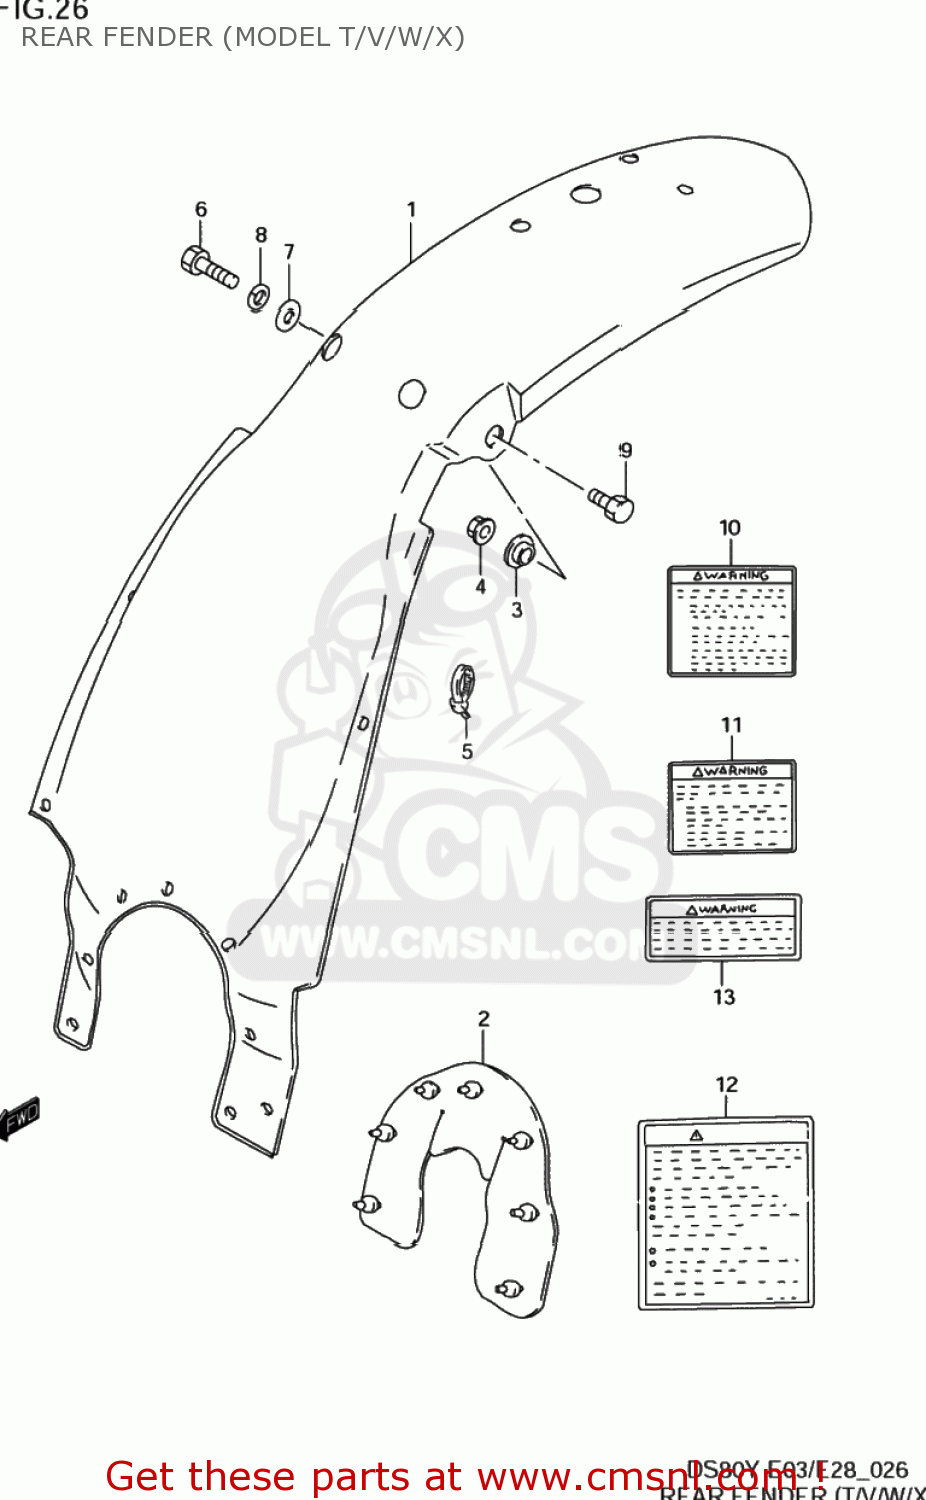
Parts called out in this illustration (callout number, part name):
1	FENDER,RR
2	MUDGUARD,RR FENDER
3	WASHER
4	NUT
5	CLAMP
6	BOLT
7	WASHER(8.5X28X1.6)
8	LOCK WASHER
9	BOLT
10	LABEL (WARNING)
11	LABEL, WARNING
12	LABEL, ATTENTION
13	LABEL (MANUAL NOTICE)
14	MANUAL, OWNER'S
